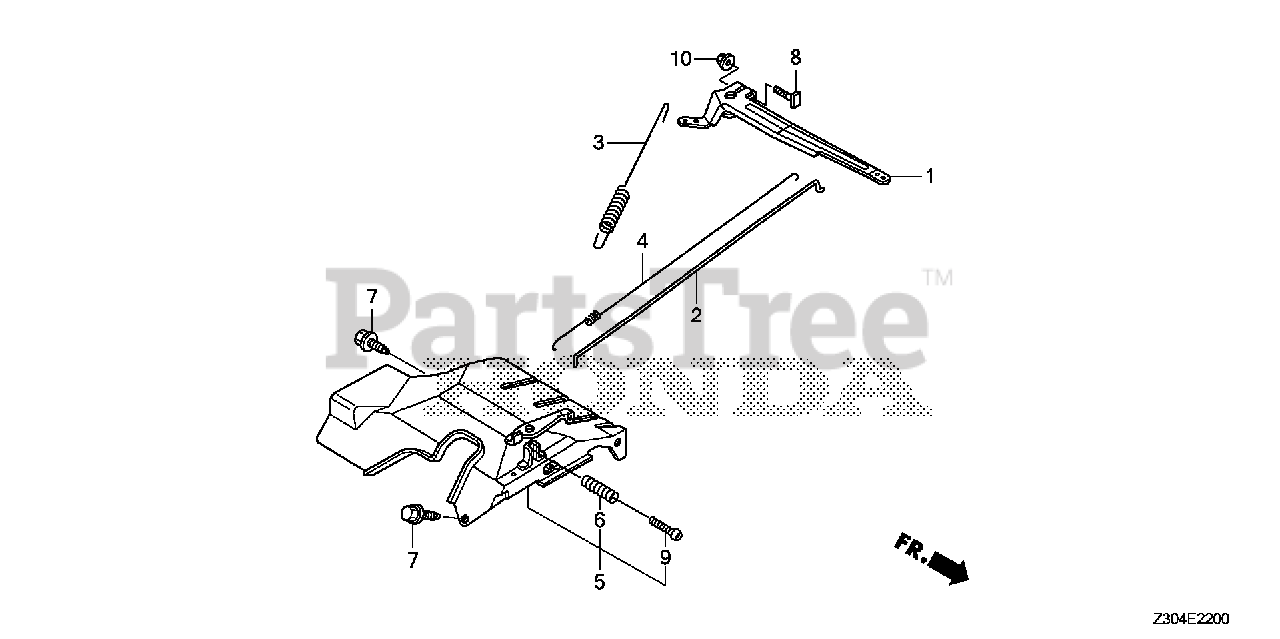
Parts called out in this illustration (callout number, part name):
1	ARM, GOVERNOR
2	ROD, GOVERNOR
3	SPRING, GOVERNOR
4	SPRING, THROTTLE RETURN
5	CONTROL ASSY. (COO)(FOR U.S.A.)
6	SPRING, CONTROL ADJUSTING
7	BOLT, FLANGE (6X12) (CT200)
8	BOLT, GOVERNOR ARM
9	SCREW, PAN (5X35)
10	NUT, FLANGE (6MM)
